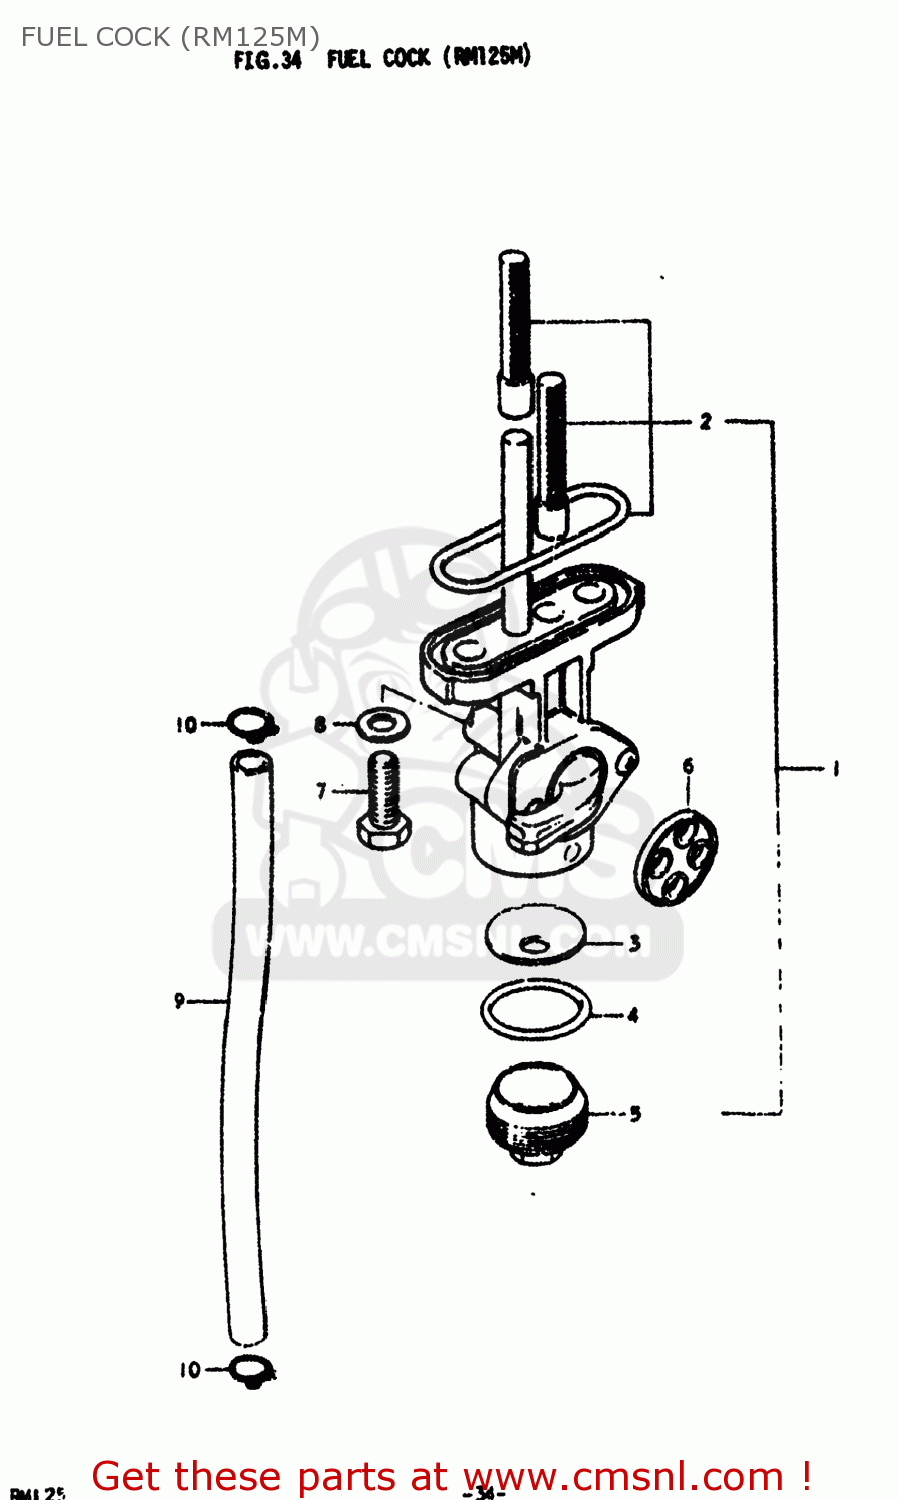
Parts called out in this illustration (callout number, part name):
1	COCK ASSEMBLY,FUEL
2	FILTER SET,FUEL COCK
3	NET,STRAINER
4	GASKET,FILTER (NAS)
5	CUP,FUEL COCK STRAINER
6	GASKET,LEVER (NAS)
7	SCREW
8	GASKET
9	HOSE
10	CLIP
